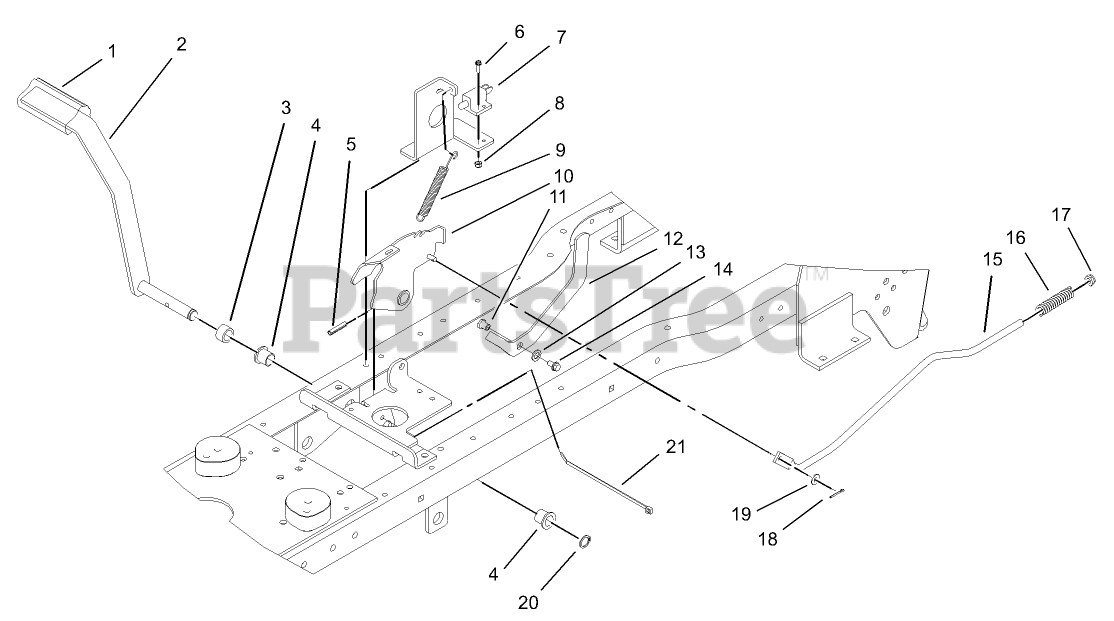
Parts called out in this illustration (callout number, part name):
1	PAD-PEDAL
2	BRAKE PEDAL ASM
3	SPACER-BRAKE
4	BUSHING-FLANGE
5	PIN-SPRING
6	SCREW-SHH
8	NUT-LOCK
10	BRAKE ASM
11	POST-MOUNTING, LINKAGE
12	LEVER-BRAKE, PARKING
13	SPACER-BRAKE, PARKING
14	SCREW-HHF
15	ROD-BRAKE
16	SPRING-COMPRESSION
17	NUT-HEX
18	PIN-COTTER
19	WASHER-FLAT
20	RING-RETAINING
21	TIE-CABLE
